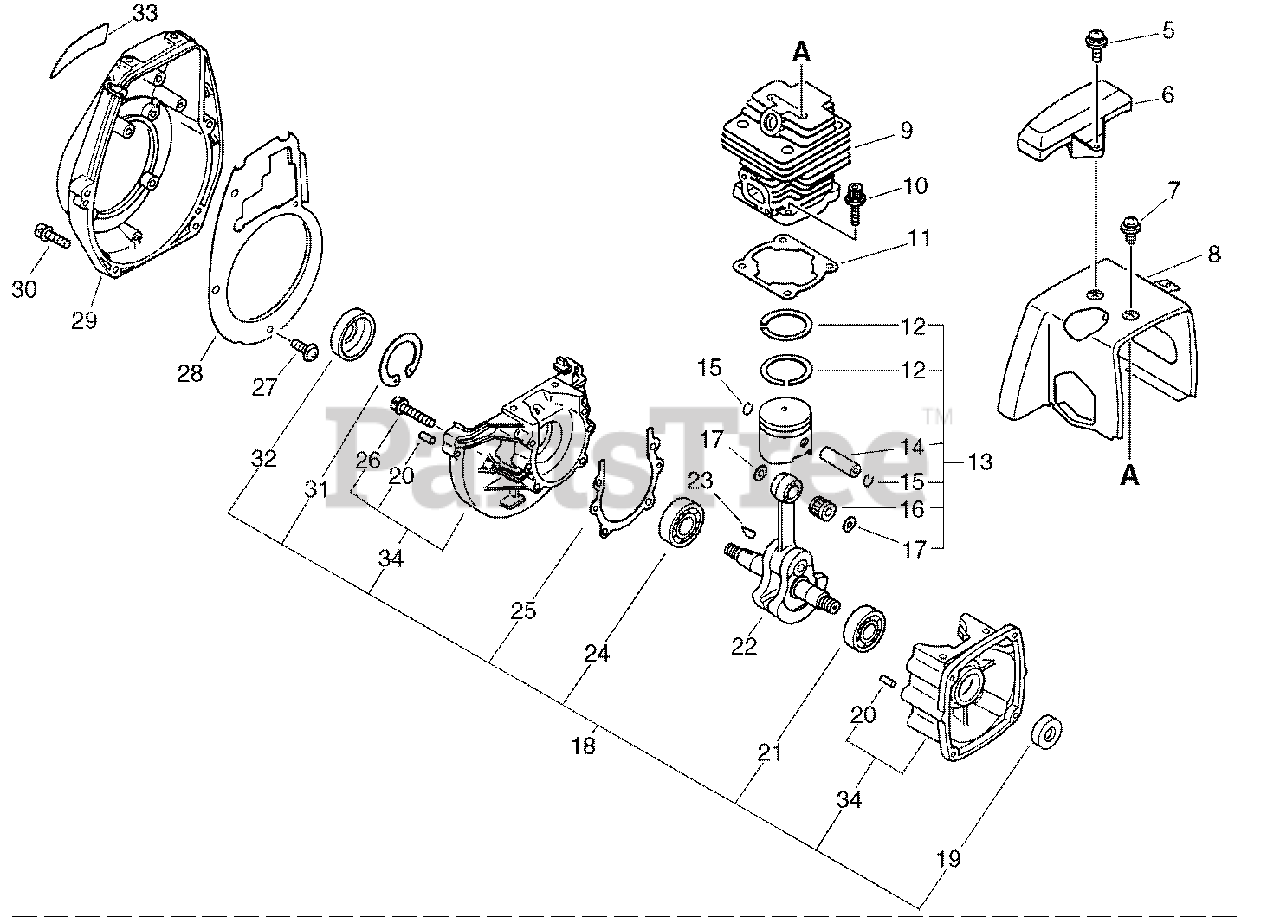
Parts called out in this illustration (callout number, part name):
5	SCREW - 5X14
6	GUARD - TOP
7	SCREW - 5X10
8	COVER, ENGINE - ORANGE
9	CYLINDER
10	SCREW - 5X20
11	GASKET, CYLINDER
12	RING, PISTON
13	PISTON KIT
14	PIN, PISTON
15	RING, RETAINING
16	BEARING, NEEDLE
17	WASHER - 10
18	CRANKCASE KIT
19	SEAL, OIL - 12
20	PIN - LOCATING
21	BEARING, BALL - 6201
22	CRANKSHAFT ASSY
24	BEARING, BALL - 6202
25	GASKET, CRANKCASE
26	SCREW - 5X30
27	SCREW - 4X10
28	SHIELD, FAN
29	COVER, FAN - ORANGE
30	SCREW - 5X25
31	RING, RETAINING - 35
32	SEAL, OIL
33	LABEL - MODEL
34	CRANKCASE KIT
